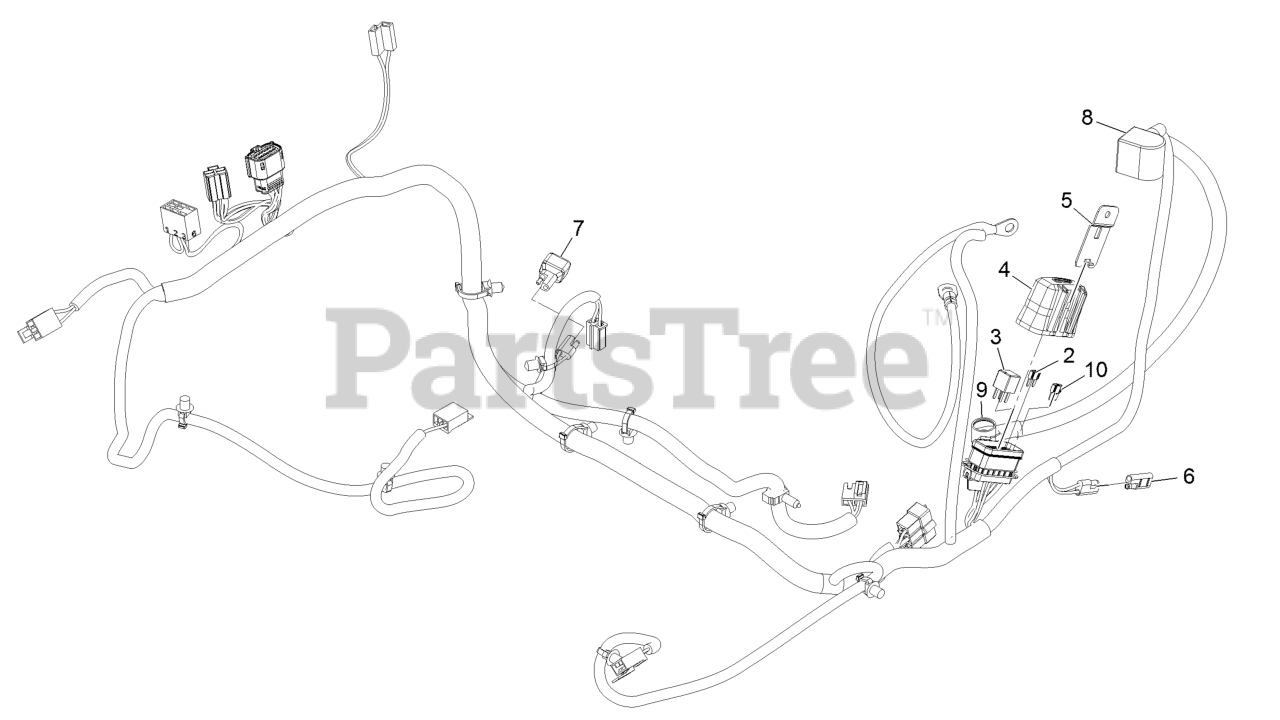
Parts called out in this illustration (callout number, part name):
2	Fuse-Mini Blade, 20 Amp
3	Relay-Micro
4	Cover-Block, Fuse
5	Clip-Mounting
6	Cap-Plug
8	Insulator-Battery
9	Insulator-Solenoid
10	Fuse-Mini Blade, 15 Amp
